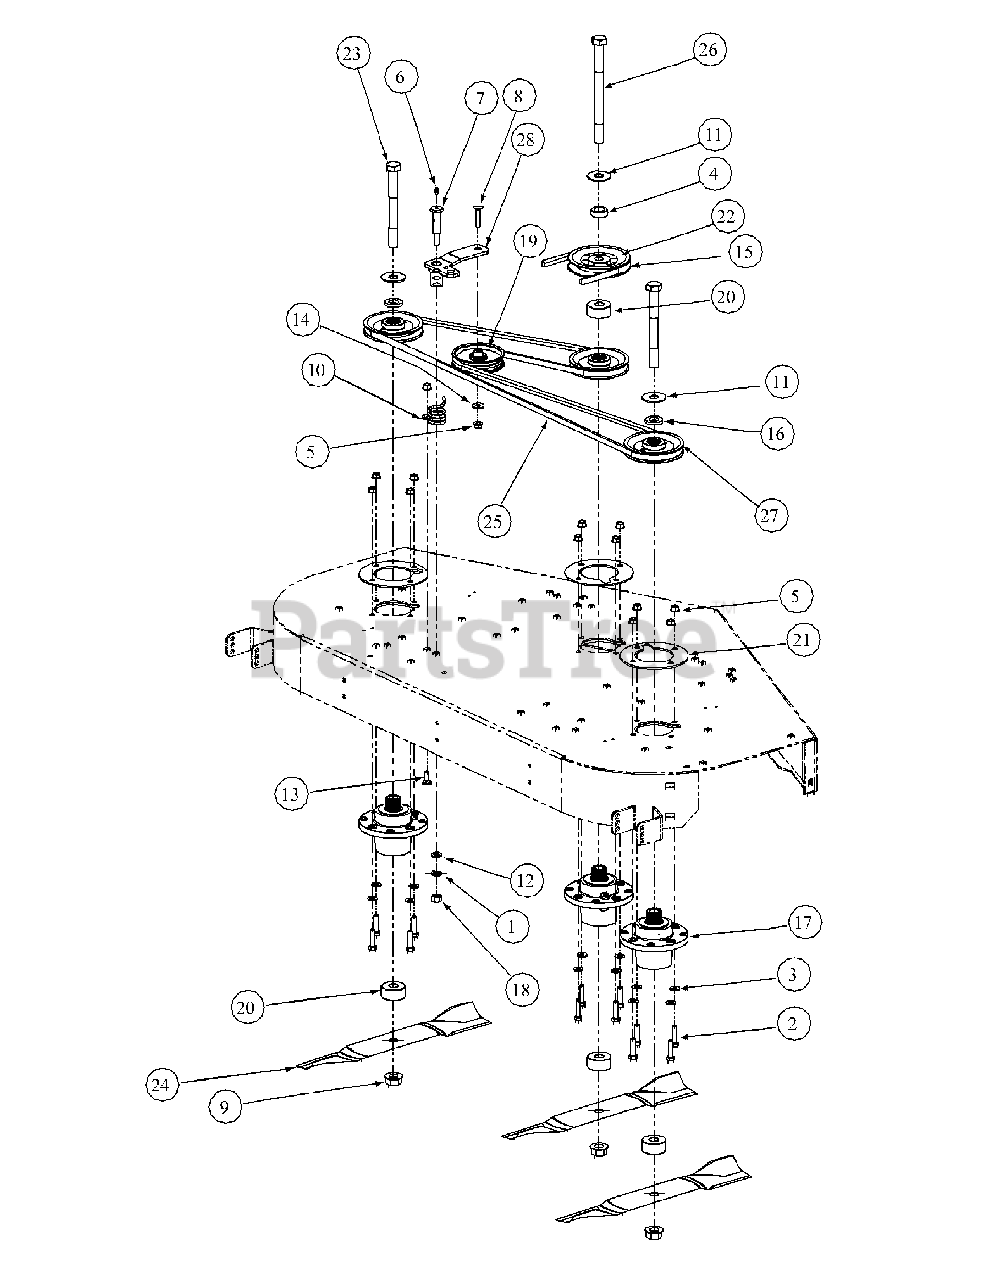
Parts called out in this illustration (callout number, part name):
1	Lock Washer, 1/2
2	Hex Head Cap Screw, 3/8-16 x 1-1/2
3	Flat Washer, 3/8
5	Flange Lock Hex Nut, 3/8-16
6	Grease Fitting, 1/4-28 x 3/16
7	Shoulder Screw, 7/16-14
8	Hex Carriage Screw, 3/8-16, 1.75
9	Flange Hex Nut,3/4-16
10	Idler Torsion Spring
11	Flat Washer, .781 ID, 2.00 OD, .105
12	Flat Washer, .469 ID, .875 OD, .105
13	Carriage Bolt, 3/8-16 x 1
14	Flat Washer, .406 ID, 1.0 OD, .105
15	Belt, B Section x 65.04
16	Spacer, .812 ID x .268 Lg
17	Aluminum Spindle Assembly
18	Hex Nut, 1/2-20
19	Flat Pulley with Flanges
20	Spacer, .760 ID x 2.00 OD x 0.9
21	Aluminum Spindle Support Plate
22	Cast Pulley, 5.25 OD
23	Hex Cap Screw, 3/4-16, 7.00
24	Hi-Lift Blade, 19.0,.756 ID
25	Belt, A Section x 114.3
26	Hex Cap Screw, 3/4-16, 9.00
27	Cast Pulley, 4.65 OD
28	Idler Arm Assembly Bearing
